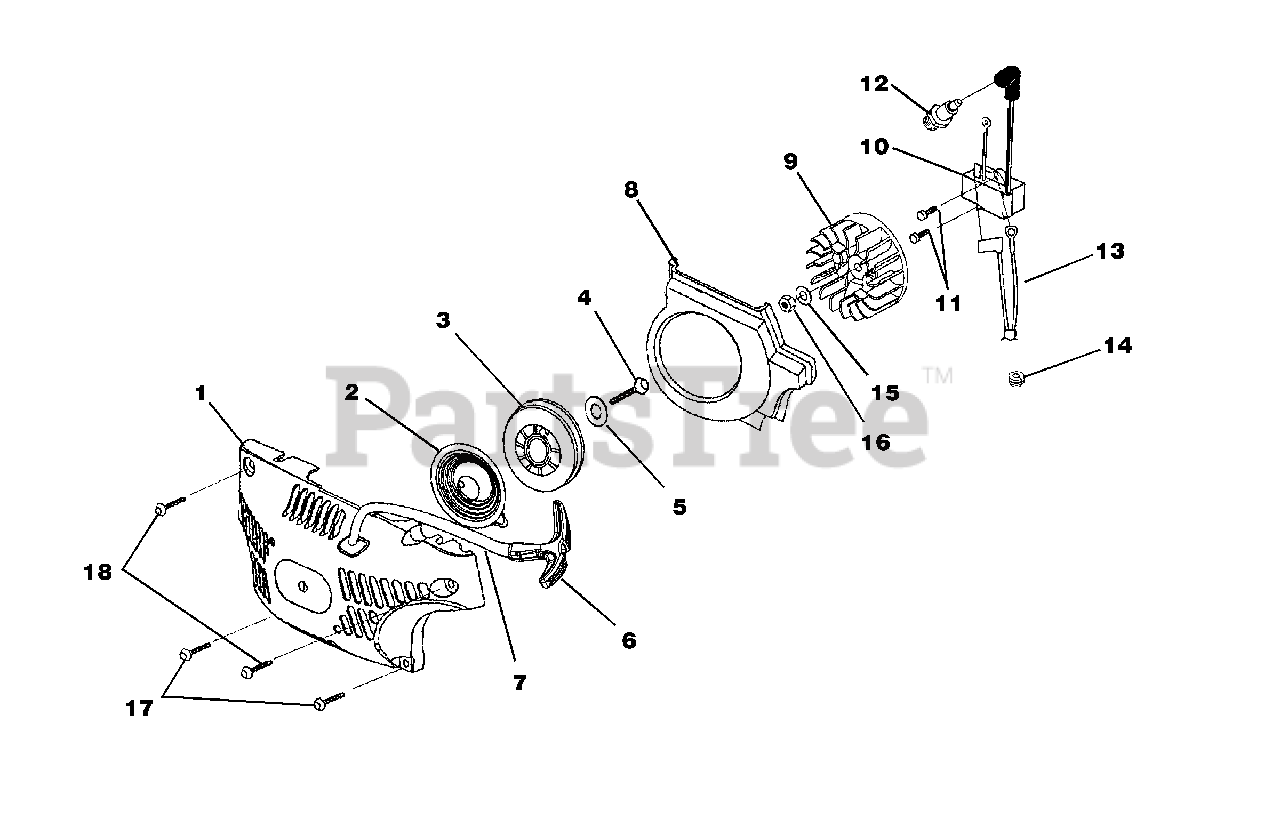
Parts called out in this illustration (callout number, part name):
1	Starter Kit
2	Spring & Container
3	Pulley, Starter
4	Screw, Thread Form (10-14 x 5/8")
5	Washer, Retaining
6	Grip, Starter
7	Rope, Starter 46"
8	Baffle, Fan Housing
9	Rotor & Starter Pawl
10	Ignition Kit
11	Screw, Thread Form (8-32 x 5/8")
12	Spark Plug
13	Ignition Switch Harness
14	Grommet, Wire Harness (Split)
15	Washer, Flat
16	Nut, Jam
17	Screw, Truss Hd. (10-14 x 7/8")
18	Screw, Truss Hd. (10-14 x 5/8")
